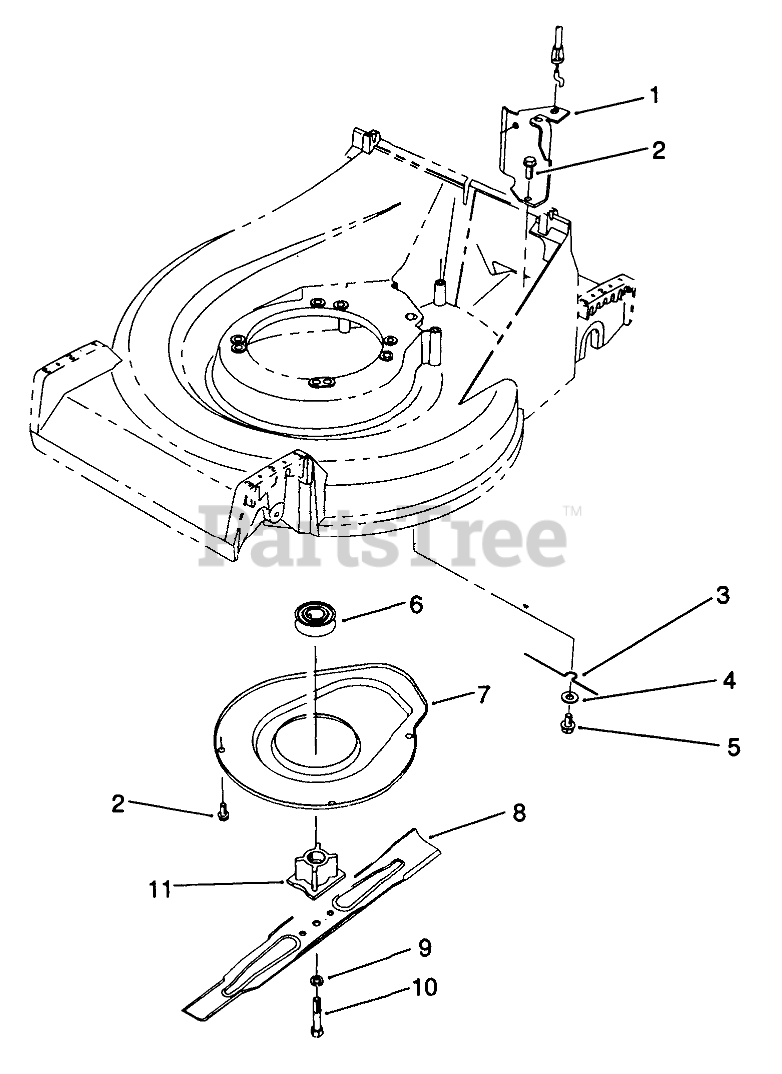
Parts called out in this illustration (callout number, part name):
1	Bracket-Cable Support
2	SCREW-HWHTF
3	RETAINER-BELT
4	WASHER-FLAT
5	SCREW-HHFTF
6	PULLEY-DRIVE, ZONE START
7	Cover
8	Key
9	WASHER-LOCK
10	SCREW-BLADE
11	BLADE RETAINER
